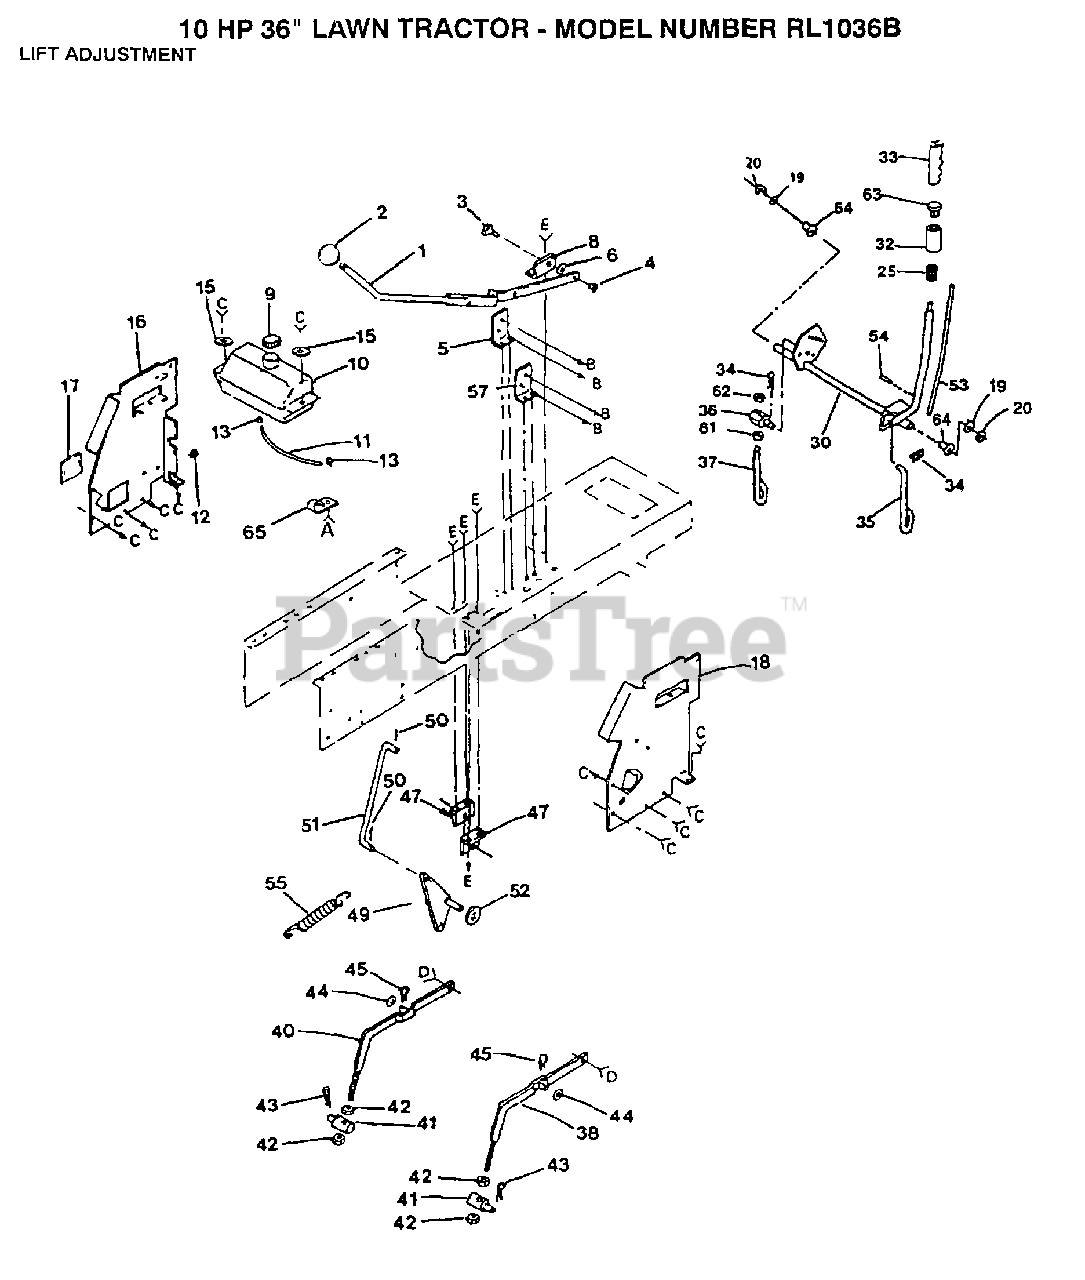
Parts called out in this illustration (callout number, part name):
3	"BOLT, SHOULDER LT"
5	"BRACKET,SWITCH LT"
7	SCREW
8	"SUP,LVR,CLUTCH LT"
10	TANK.FUEL.LT.
11	FUEL LINE T
12	SNAP BUSHING T
13	HOSE CLAMP
14	SCREW
15	WASHER GT
16	PANEL DASH LH
17	COVER ACCESS
19	WASHER
21	SCREW LT
33	GRIP
35	LIFT LINK LT
37	PIVOT PIN T
38	RH SUSP ARM ASM
39	"BOLT, SHOULDER LT"
40	LH SUSP ARM ASM
42	NUT
43	SPRING H
45	SPRING.RETAINER
47	"BRKT,BELLCRAN T"
49	"T, BELLCRANK"
50	COTTER PIN
52	WASHER
54	PIN-GROOVE LT
57	BRACKET LT
59	WASHER T
60	NUT SPECIAL T
61	NUT
64	NYLON BEARING
65	INSUL CLIP T
